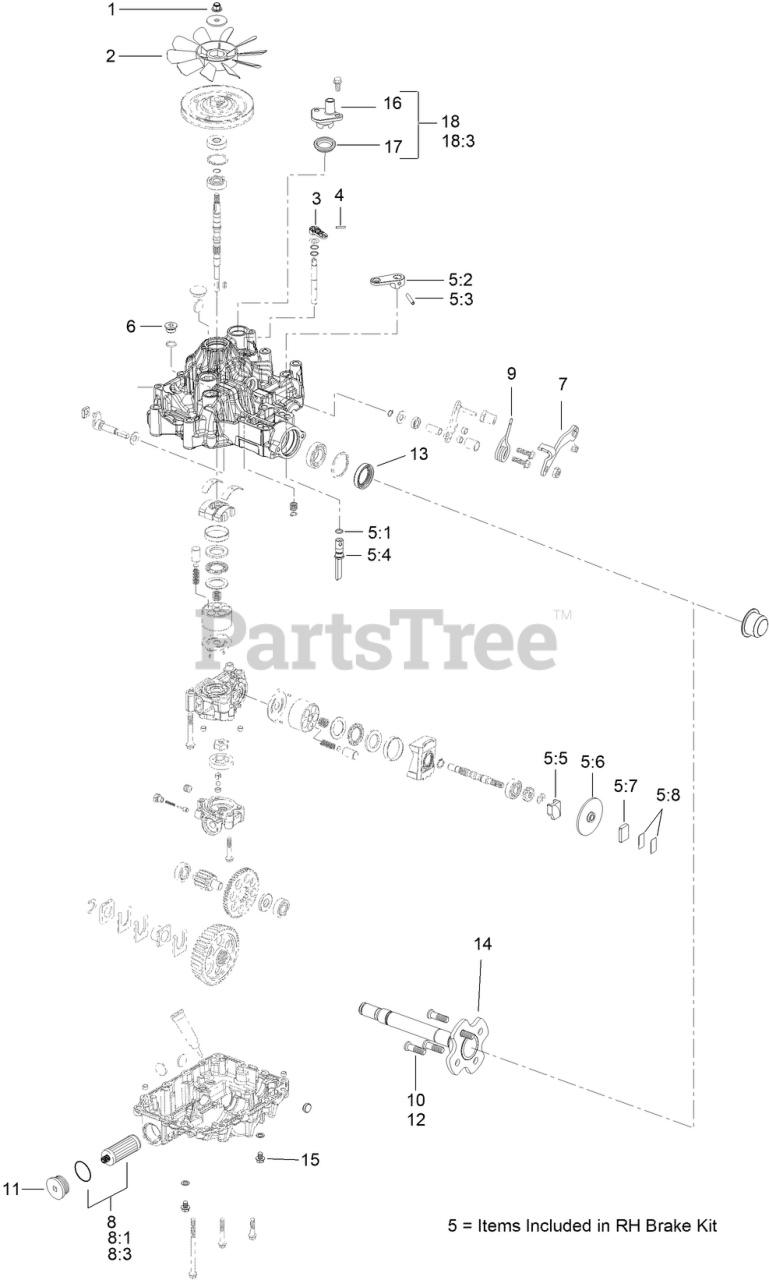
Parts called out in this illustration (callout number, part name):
1	NUT-LOCK
4	LEVER-BYPASS
5	BRAKE KIT,LEFT
5:1	O-RING
5:2	BRAKE ARM
5:3	Roll Pin
5:4	BRAKE SHAFT
5:5	BRAKE ACTUATOR
5:6	Brake Disc
5:7	BRAKE SHOE
5:8	SHIM KIT
6	CAP-OIL
7	LEVER-CONTROL, RH
8	2 TRANSMISSION FILTER KIT
8:3	SEALING WASHER
9	SPRING-TORSION
10	STUD-WHEEL
11	CAP-OIL FILTER
12	STUD-WHEEL
13	SEAL-AXLE, UA
15	DRAIN BOLT
16	EXPANSION FITTING
17	GROMMET SEAL, EXPANSION FITTING
18	EXPANSION FITTING - W/ SEAL
18:3	M8*20 FLANGE BOLT
